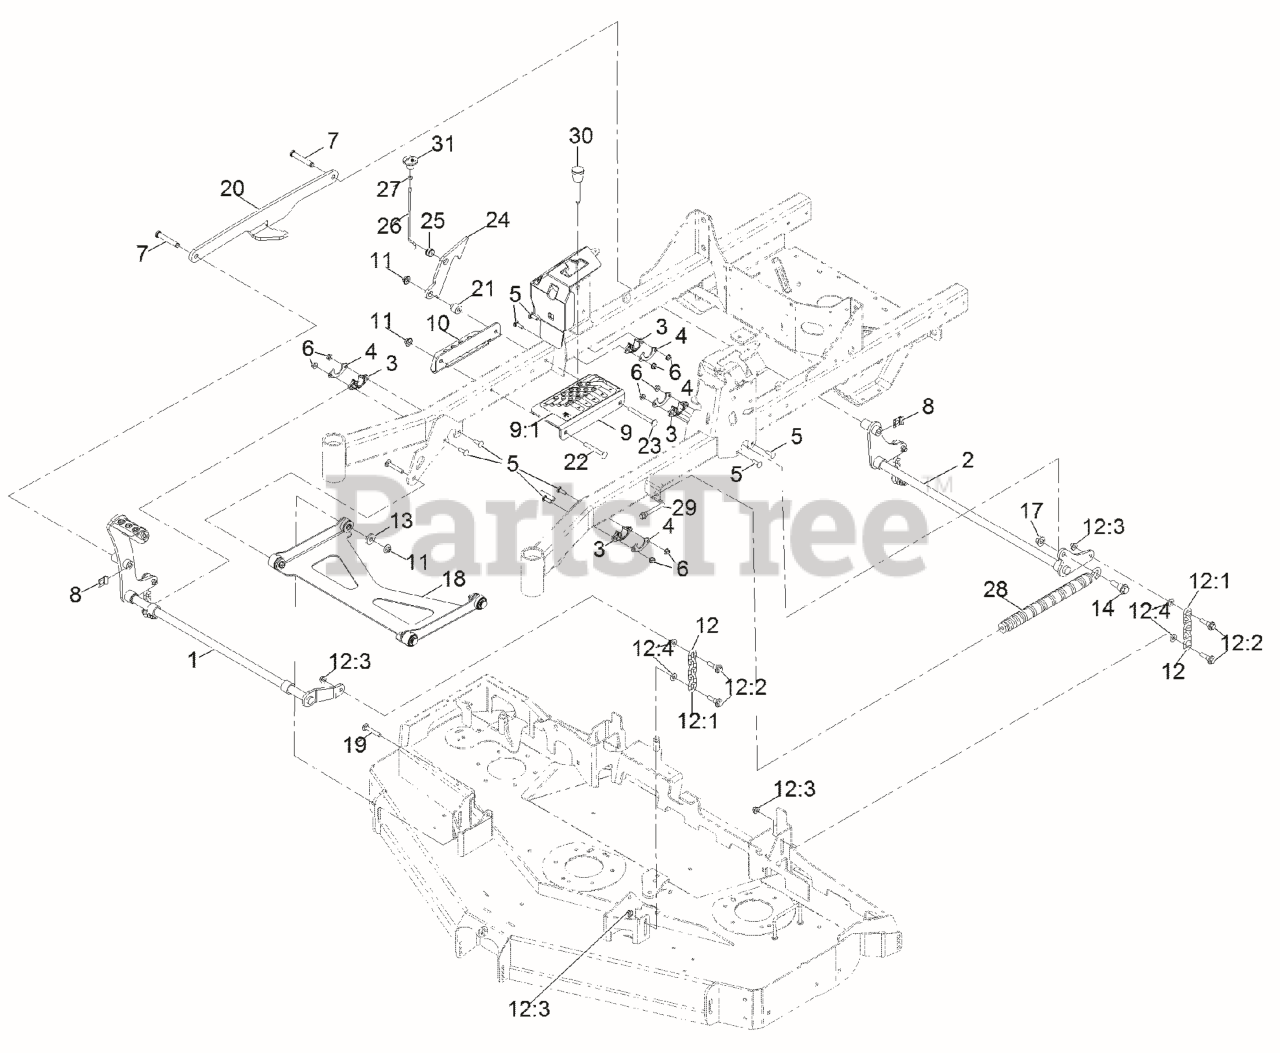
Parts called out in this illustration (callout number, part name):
1	SHAFT-LIFT, DECK
2	SHAFT-LIFT, DECK (REAR)
3	BUSHING-FLANGE
4	GUSSET-LIFT, DECK
5	SCREW-CARR
6	NUT-HF, NI
7	PIN-CLEVIS
8	CLIP-PIN
9	BRACKET ASM
9:1	DECAL-HOC
10	ANGLE-HOC, LOWER
11	Nut-Nyloc 3/8-16 Flg
12	DECK CHAIN ASM
12:1	CHAIN-LIFT, DECK
12:2	BOLT-SHOULDER
12:3	NUT-HF, NI
14	SCREW-SHOULDER, HHF 1/2-13 X 1.12
17	Nut-Lock 1/2-13
18	DECK STRUT ASM
19	Bolt-Carriage 3/8-16 X 2 1/4
20	LINK-LIFT
21	SPACER-STEPPED
22	SCREW-CARR
23	SCREW-CARR
24	PLATE-LOCK, TRANSPORT
25	GROMMET
26	ROD-LOCK, TRANSPORT
27	NUT-JAM
28	SPRING-EXTENSION
29	BOLT-SHOULDER
30	PIN-HOC
